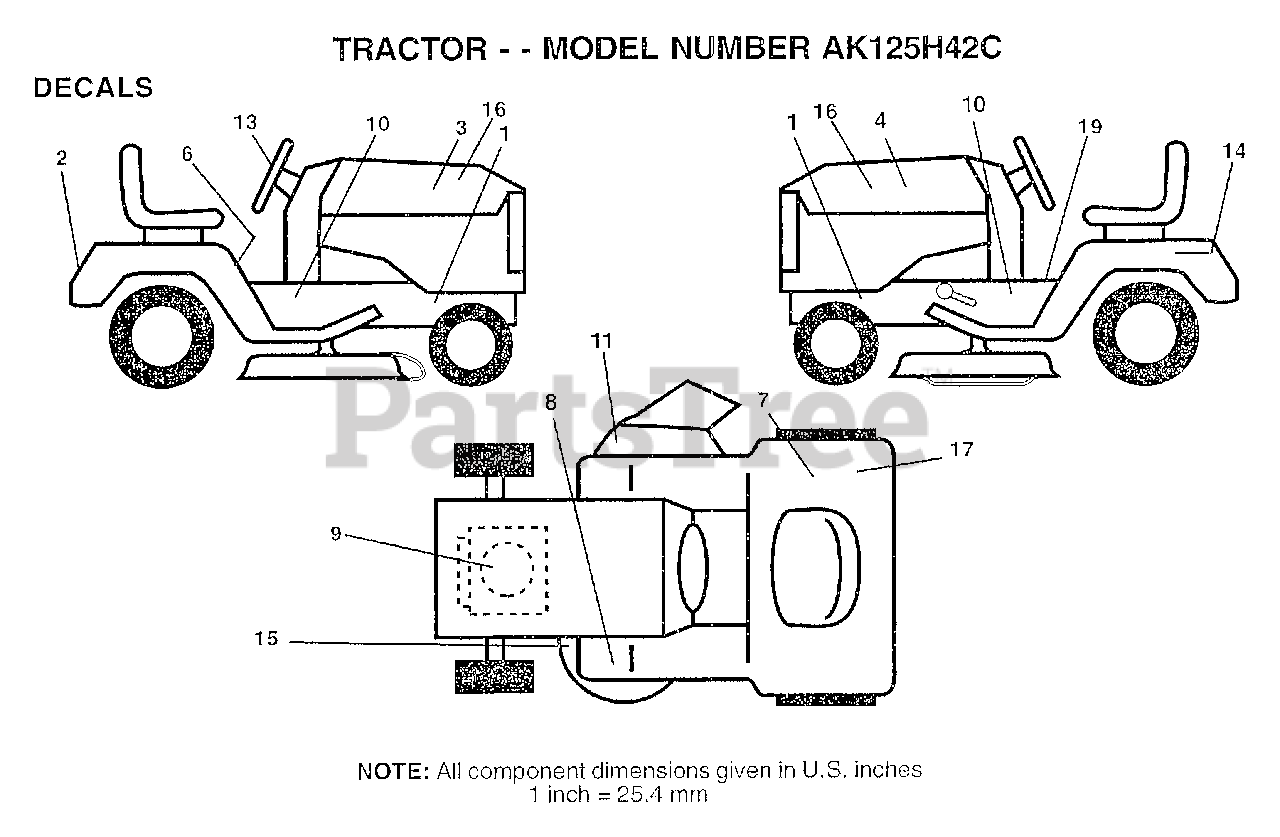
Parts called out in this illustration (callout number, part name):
1	"DECAL CHASSIS,HOT"
2	DECAL FENDER
3	DECAL HOOD RH
4	DECAL HOOD LH
6	DECAL.READ.O.MANU
7	DECAL.EURO.ST.CE.
8	DECAL-BRAKE/CLUTC
9	DECAL, ENGIN
10	DECAL CHAS 42 HYD
11	DECAL.DANGER.CUTF
13	"DECAL,STR WHL"
14	DECAL.BATRY.3-3908
15	"DECAL-SCHEM,BELT"
19	DECAL BRAK PARK
